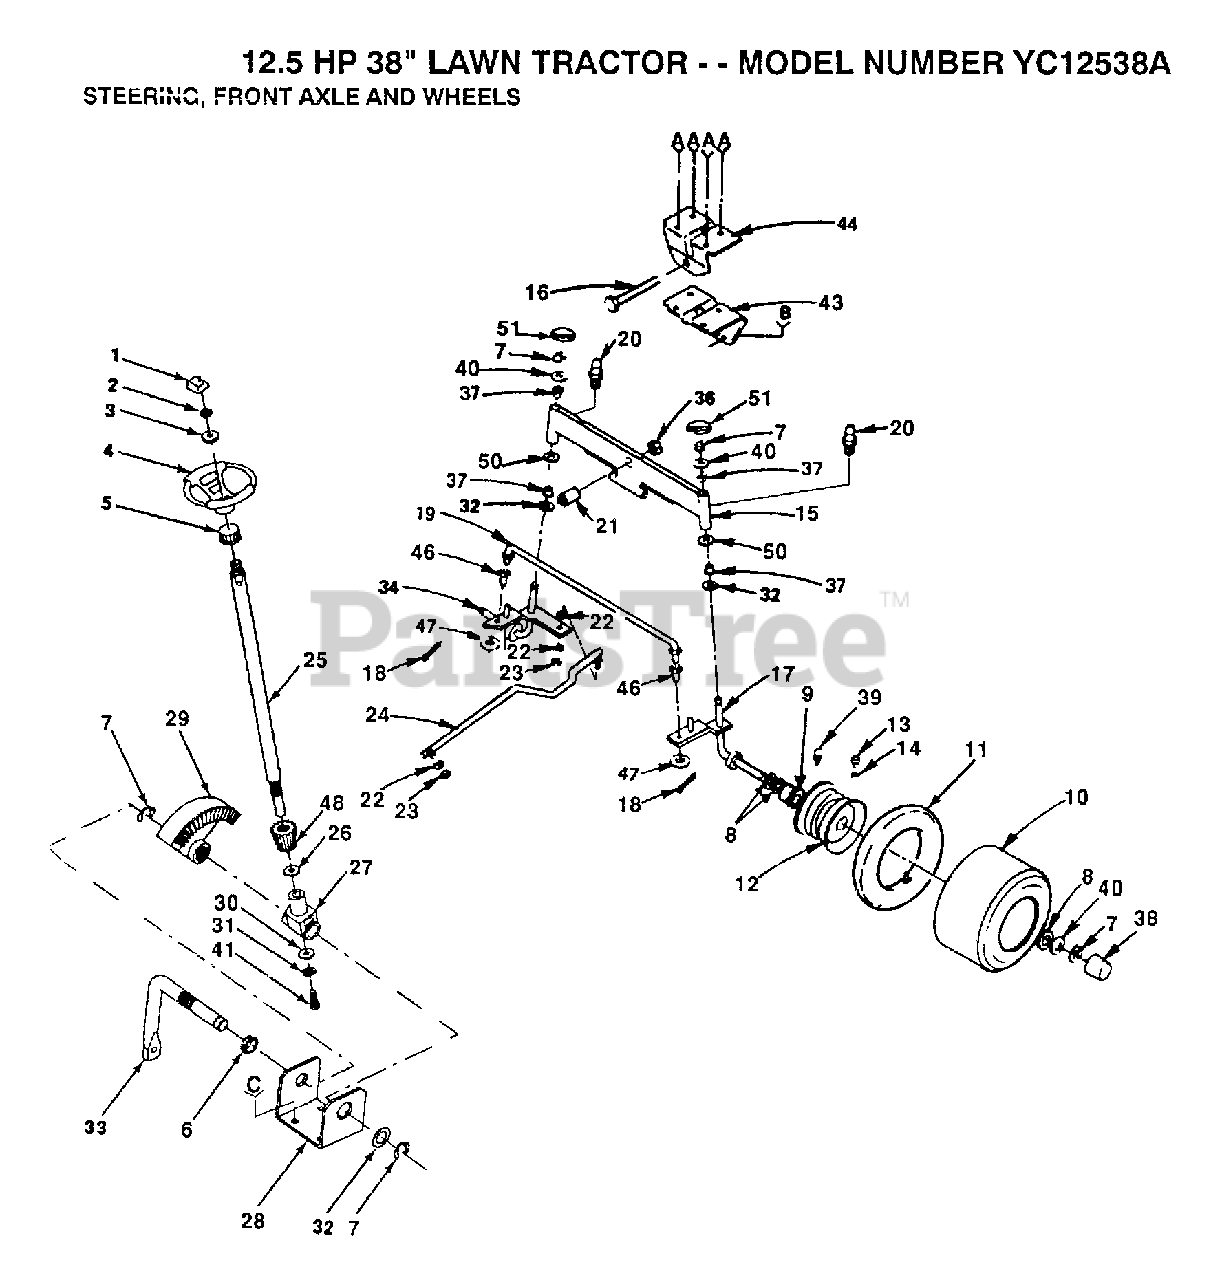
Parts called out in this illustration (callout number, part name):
1	INSERT STEERING
3	WASHER
5	ADAPTER LT
6	NYLINER T
7	RING
8	WASHER
9	"FLANGE, BEARING"
11	TUBE.5.3/4.5/6
13	VALVE STEM LT
14	VALVE CAP
15	FRONT AXLE
16	BOLT LT
18	COTTER PIN
20	ZERK M
21	BEARING
22	LOCKWASHER
26	THRUST WASHER
27	SUPPORT.SHAFT
28	"BRKT,STEERING"
31	LOCKWASHER
32	WASHER .T
34	SPINDLE-LH LT
36	"NUT-LOC,FLANGE LT"
37	COL. SRTG. BEAR.
38	HUB CAP
39	FITTING LT
40	WASHER
41	"SCREW,SPECIAL"
43	SUPPORT.SADDLE.FT
44	SUPPORT-SADDL T
47	WASHER
48	"GEAR,PINION"
50	WASHER
51	CAP
